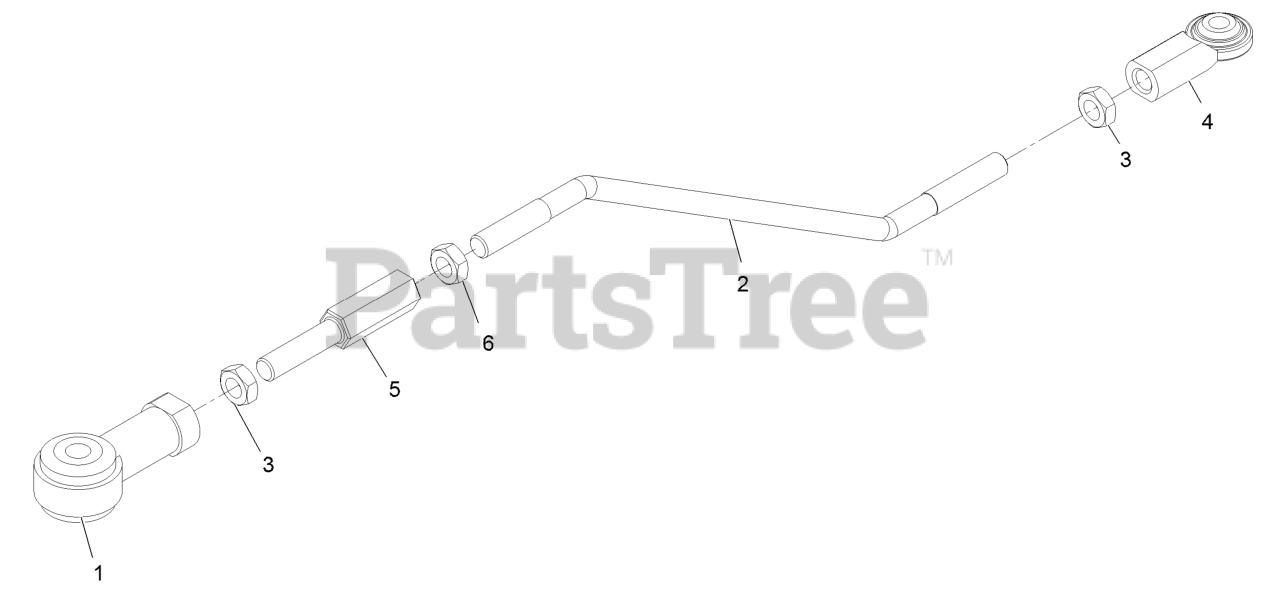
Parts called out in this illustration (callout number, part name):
1	End-Rod, Isolated
2	Rod-Linkage, Rear
3	Nut-Jam 3/8-24
4	Balljoint
5	Rod-Adjustment
6	Nut-Jam 3/8-24 LH
